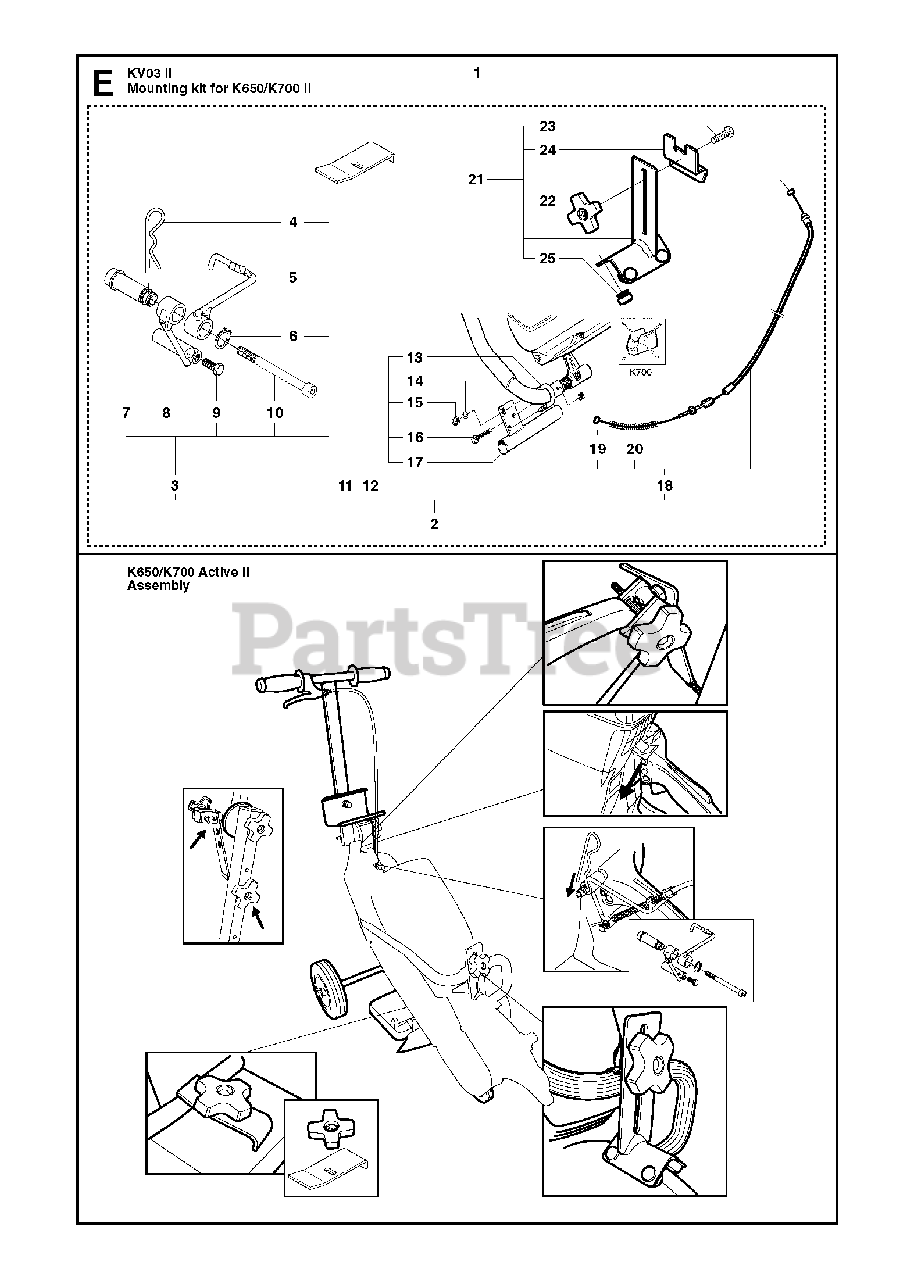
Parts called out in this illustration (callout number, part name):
1	ASSEMBLY KITIncl. 2, 21
2	CUTTING TROLLEYIncl. 3, 11, 12, 18
3	KITIncl. 4 - 10
11	PRESSURE PLATE
16	SCREW IHSCFM
18	THROTTLE WIREIncl. 19, 20
21	RETAINERIncl. 22 - 25
22	STEERING WHEEL
